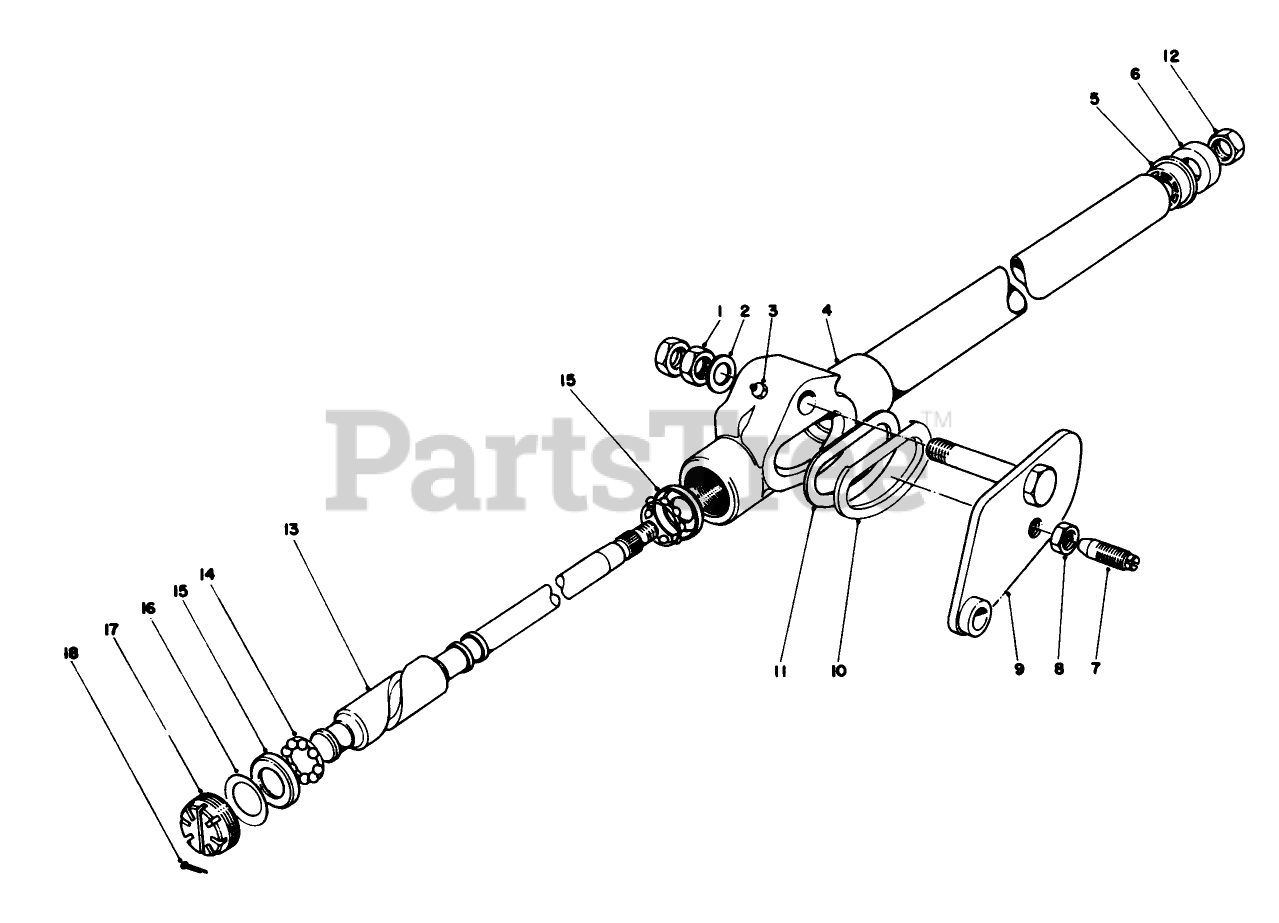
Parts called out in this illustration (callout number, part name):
1	NUT-JAM
2	Washer
3	ZERK FITTING
4	Inner Tunnel
5	Column Bearing
6	COVER-DUST
7	LEVER STUD
8	NUT-HEX
9	LEVER & BOLT ASM
10	SEAL RETAINING
12	NUT-JAM
13	Cam & Tube Assembly
14	RETAINER & BALL ASM
15	BalI Cup
16	WASHER-BELLEVILLE
17	ADJUSTING PLUG
18	PIN-COTTER
